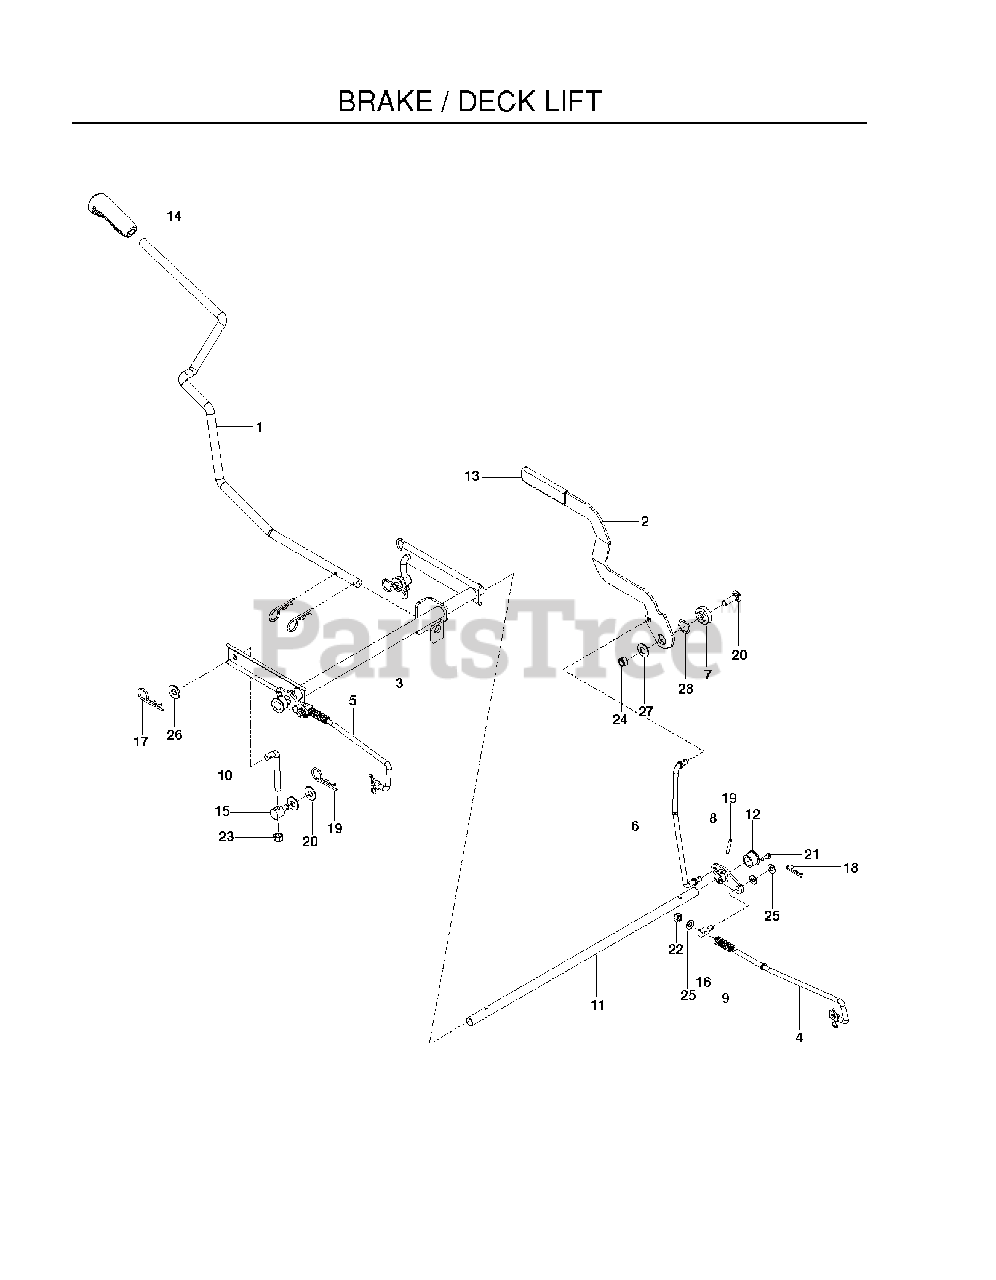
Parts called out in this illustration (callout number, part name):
1	ARM, LIFT HANDLE, BLK
2	HANDLE, BRAKE, BLK
3	SHAFT, LIFT WLDMT, BLACK
4	LINKAGE, EZT BRAKE RT
5	LINKAGE, EZT BRAKE LT
6	LINKAGE, BRAKE, UPPER
7	BRAKE ARM PIVOT
8	BELLCRANK, BRAKE
10	L ROD 3-1/8"
11	ROD, BRAKE
12	PLASTIC BUSHING
13	GRIP BRAKE HANDLE
14	GRIP.LEVER.5625.ID
16	BRAKE SWIVEL
17	HAIRPIN #4
18	HAIRPIN #2
19	ROLL PIN 3/16 X 1-1/4 ZD
20	RHSNB 3/8-16 X 1-1/4
21	SCREW #10 X 1/2 SELF TAPPING
22	NUT 5/16 NYLOC
23	NUT 3/8-16 NYLOC
24	NUT HEX 3/8-16 NYLON, THIN
25	FLAT WASHER 5/16 SAE
26	RP WASHER 3/8 FLAT
27	WASHER, 7/16 DISC SPRING
28	WASHER, .825 X 1.087, WAVE
